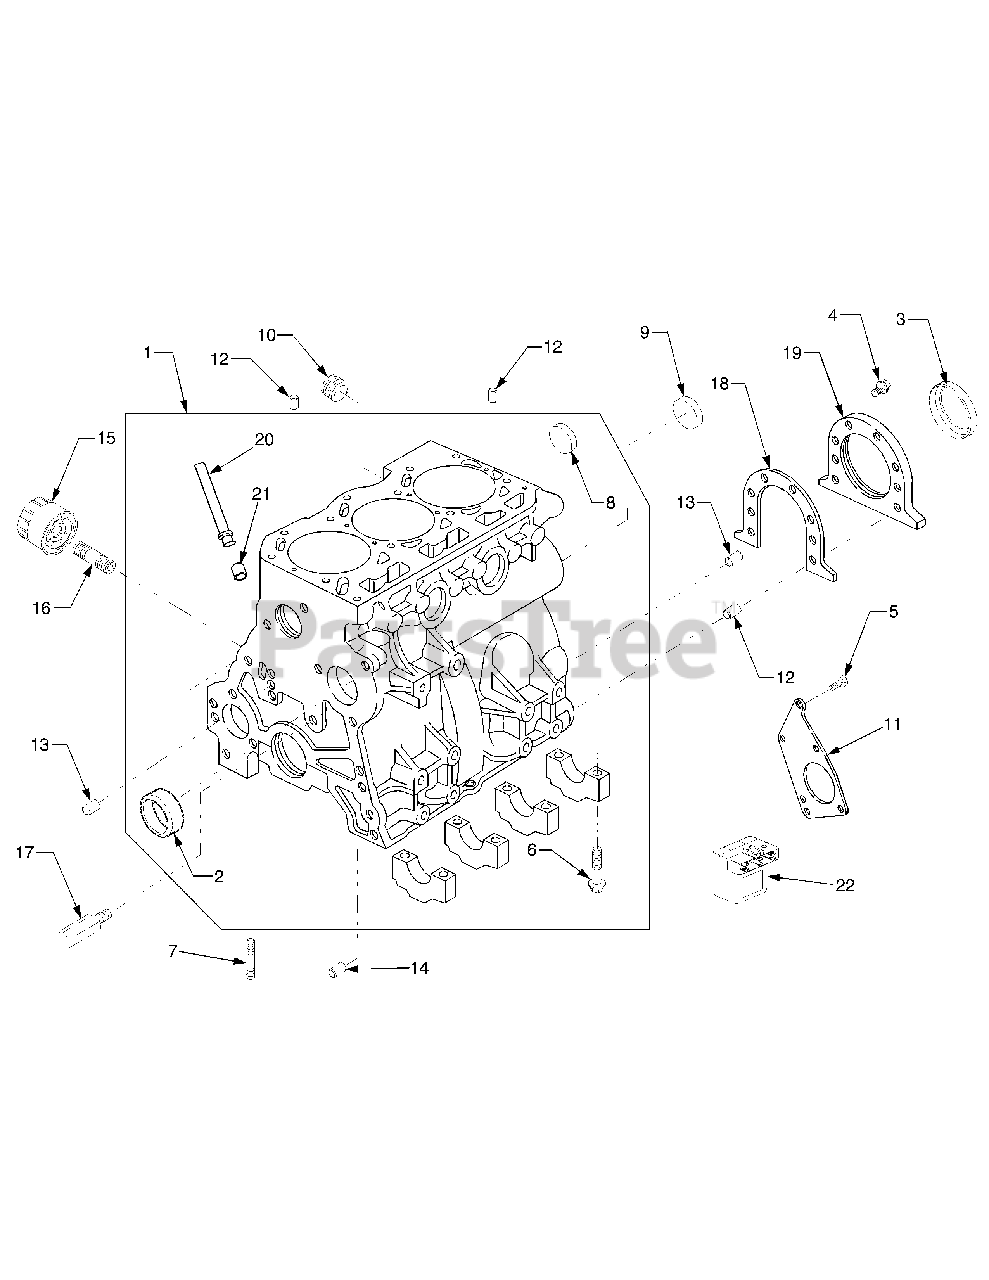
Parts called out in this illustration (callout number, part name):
1	Service Engine
2	Bushing
3	Seal, Oil
4	Screw, Hex, 6mm
5	Screw, Hex, 10mm
6	Screw, Hex, 10mm
7	Stud, Metric
8	Plug, Welch
9	Plug, Welch Camshaft
10	Plug, Cylinder Block
11	Bracket, Mounting
12	Pin, Locating
13	Pin, Locating
14	Pin, Locating
15	Filter, Oil
16	Adapter, Oil Filter
17	Nozzle, Oil
18	Gasket, Retainer
19	Seal, Retainer
20	Tube, Dipstick
21	Collar, Dipstick Tube
22	Module-Pre Heat
